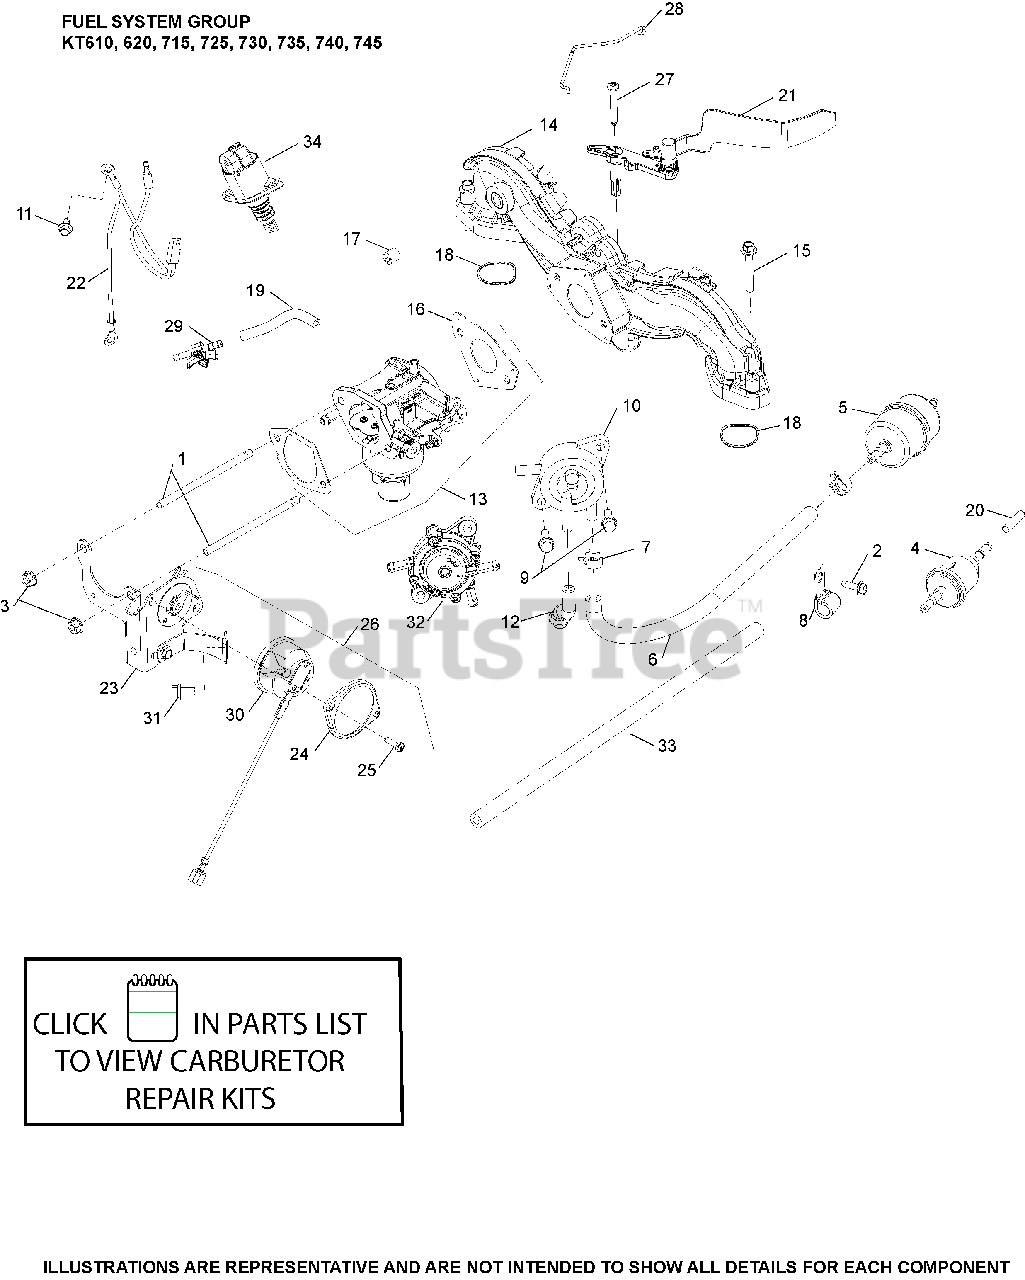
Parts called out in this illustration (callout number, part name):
3	NUT, FLG M6X1.0
4	FILTER,FUEL 51 MICRON (FUEL PUMP)
6	HOSE,LW PERM.FUEL 24.00"-USE 25 111 81-S
7	CLAMP SPRING HOSE
8	CLIP, CABLE
9	SCREW, TAP M6X1.7X18
10	PUMP, FUEL (PULSE)
11	SCREW, THREAD FORMING
12	HOSE, PULSE PUMP
13	KIT, CARBURETOR COMPLETE
14	KIT, INTAKE MANIFOLD USE 24 164 266-S
15	SCREW, FLG M6X1.0X40
16	GASKET, CARBURETOR
17	PLUG, CTSK PIPE 1/8"
18	O-RING, INTAKE PORT
